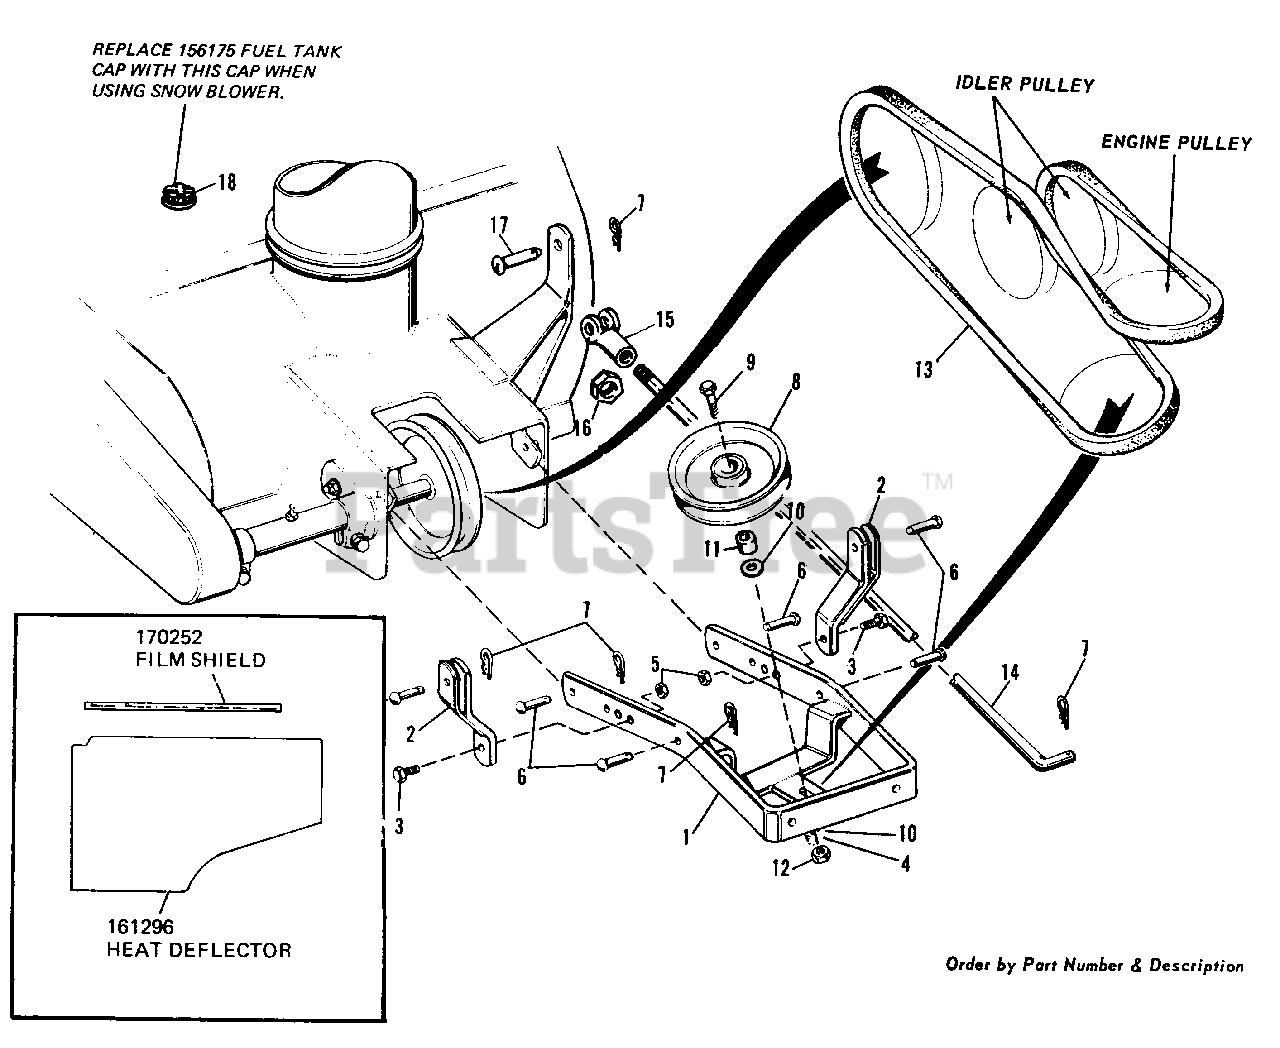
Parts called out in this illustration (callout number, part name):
1	Push Arm Assembly
2	Support Arm Assembly
3	Hex Capscrew, 3/8"-16 x 1" lg.
4	Lock Washer, 3/8"
5	Hex Nut, Full Lock 3/8"-16
7	Spring Clip
9	Hex Capscrew 3/8"-16 x 1-3/4" lg.
10	Plain Washer 3/8"
12	Hex Nut, Full 3/8"-16
14	Front Lift Rod
15	Adjusting Yoke
16	Hex Nut, Full 1/2"-20
18	Cap (Winter) Fuel Tank
19	Deflector-Heat
20	Film-Shield
